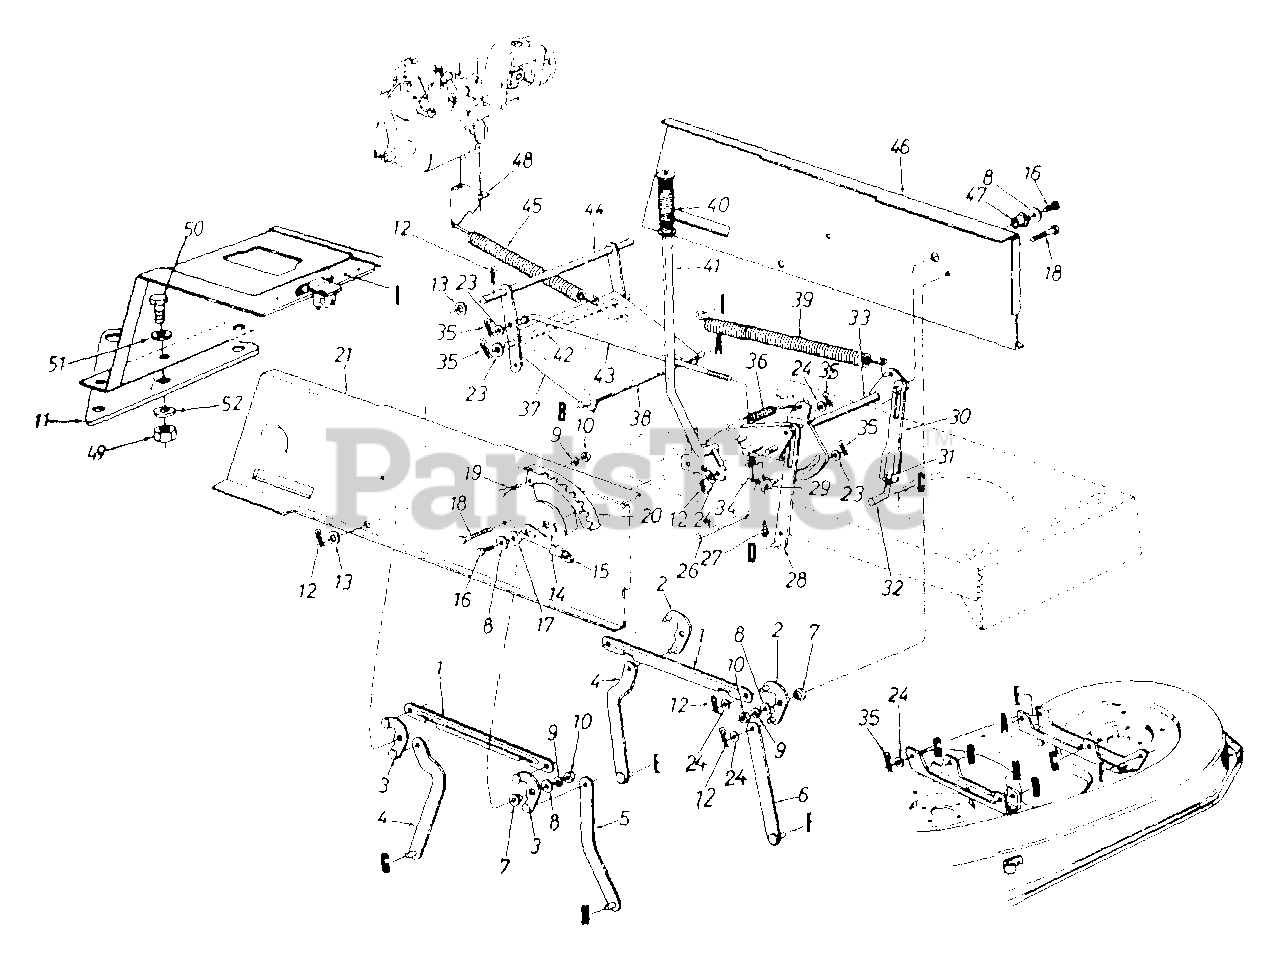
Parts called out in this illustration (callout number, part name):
1	Connecting Rod
2	Pivot Link Ass'y.- L.H.
3	Pivot Link Ass'y.- R.H.
7	Shld. Spacer .318" I.D.
8	Fl-Wash. .344" I.D. x .62" O.D.
9	L-Wash. 5/16" I.D.
10	Hex Nut 5/16-18 Thd.
11	Hitch Plate Extension
12	Cotter Pin 1/8" Dia.
13	Fl-Wash. .635" I.D. x 1.0" O.D.
14	Deck Lift - Down Stop
15	Knob
16	Hex Wash. TT-Tap Scr. 5/16-18 x .75" Lg.
17	Flange Brg. .63" I.D.
18	Hex Wash. Hd. Scr. 5/16-18 x .875" Lg.
19	Hex Bolt 5/16-18 x .75" Lg.
20	Index Brkt.
21	Upper Frame - R.H.
23	Fl-Wash. .385" I.D. x .87" O.D.
24	Fl-Wash. .531" I.D. x .93" O.D.
26	Running Board Rod
27	Truss Mach. Scr. #10 x .5" Lg.
31	Hex Nut 1/2-20 Thd. (Gr. 5)
32	Lift Link Adjuster
33	Lift Shaft Ass'y.
34	Safety Switch (Deck)
35	Inter. Cotter Pin 3/8" Dia.
36	Extension Spring
37	Stabilizer Bracket
38	Shaft 1/2" Dia. x 10.28" Lg.
39	Extension Spring
40	Grip (Lift Handle)
41	Deck Lift Handle Ass'y.
42	Shaft 3/8" Dia. x 9.34" Lg.
43	Disengagement Rod
44	Stabilizer Shaft Ass'y.
45	Extension Spring 7.58" Lg.
46	Upper Frame - L.H.
47	Flange Brg. .632" I.D.
49	Hex Nut 7/16-14 Thd. (Gr. 5)
50	Hex Bolt 7/16-14 x 1" Lg.
51	Bell-Wash. .46" I.D. x 1.13" O.D.
52	Fl-Wash. .469" I.D. x .875" O.D.
